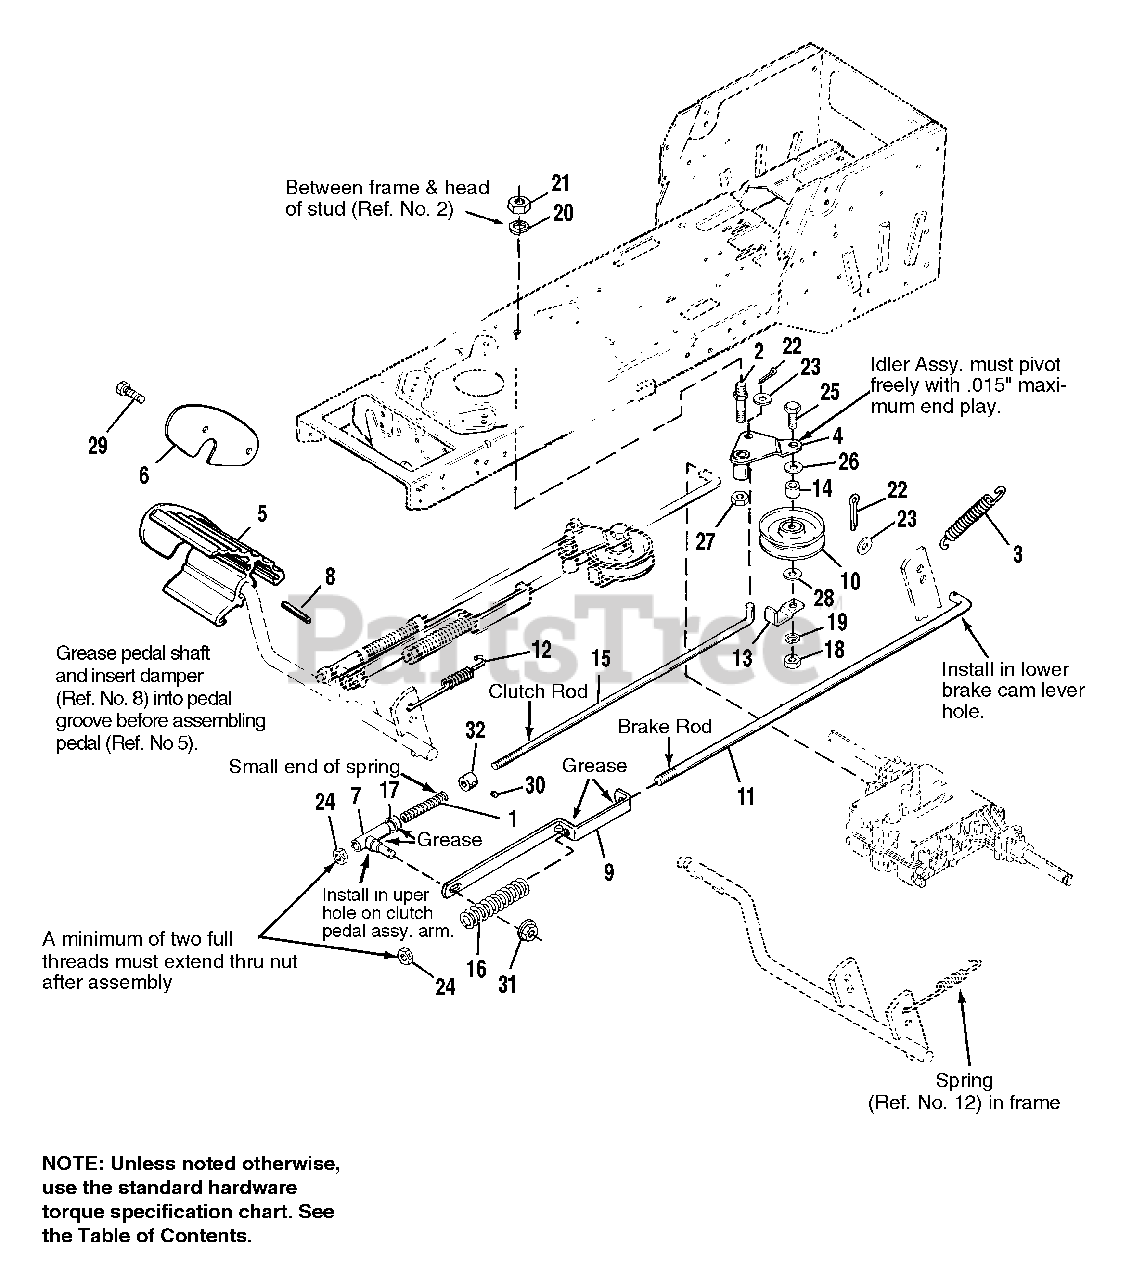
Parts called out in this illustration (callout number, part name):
1	SPRING, Compression
3	SPRING, Tension
4	IDLER ASSY.
5	PEDAL, Foot
6	PLATE, End
7	GUIDE ASSY., Rod
8	DAMPER, Rubber
12	SPRING, Return
13	GUARD, Spring
14	PULLEY ASSY.
15	ROD, Clutch
18	NUT, Hex, 3/8-16
19	LOCKWASHER, 3/8
20	LOCKWASHER, 7/16
21	NUT, Hex, 7/16-14
22	PIN, Cotter
23	WASHER, 11/32
24	LOCKNUT, 5/16-18
25	CAPSCREW, 3/8-16 x 1-1/2
26	WASHER, Plain
27	LOCKNUT, Hex, 7/16-14
28	WASHER, Plain, 5/16
29	SCREW, Taptite, 1/4-20 x 5/8
30	SETSCREW, 1/4-20 x 3/8
31	LOCKNUT, Hex, Flange, 5/16-18
32	COLLAR, Set
